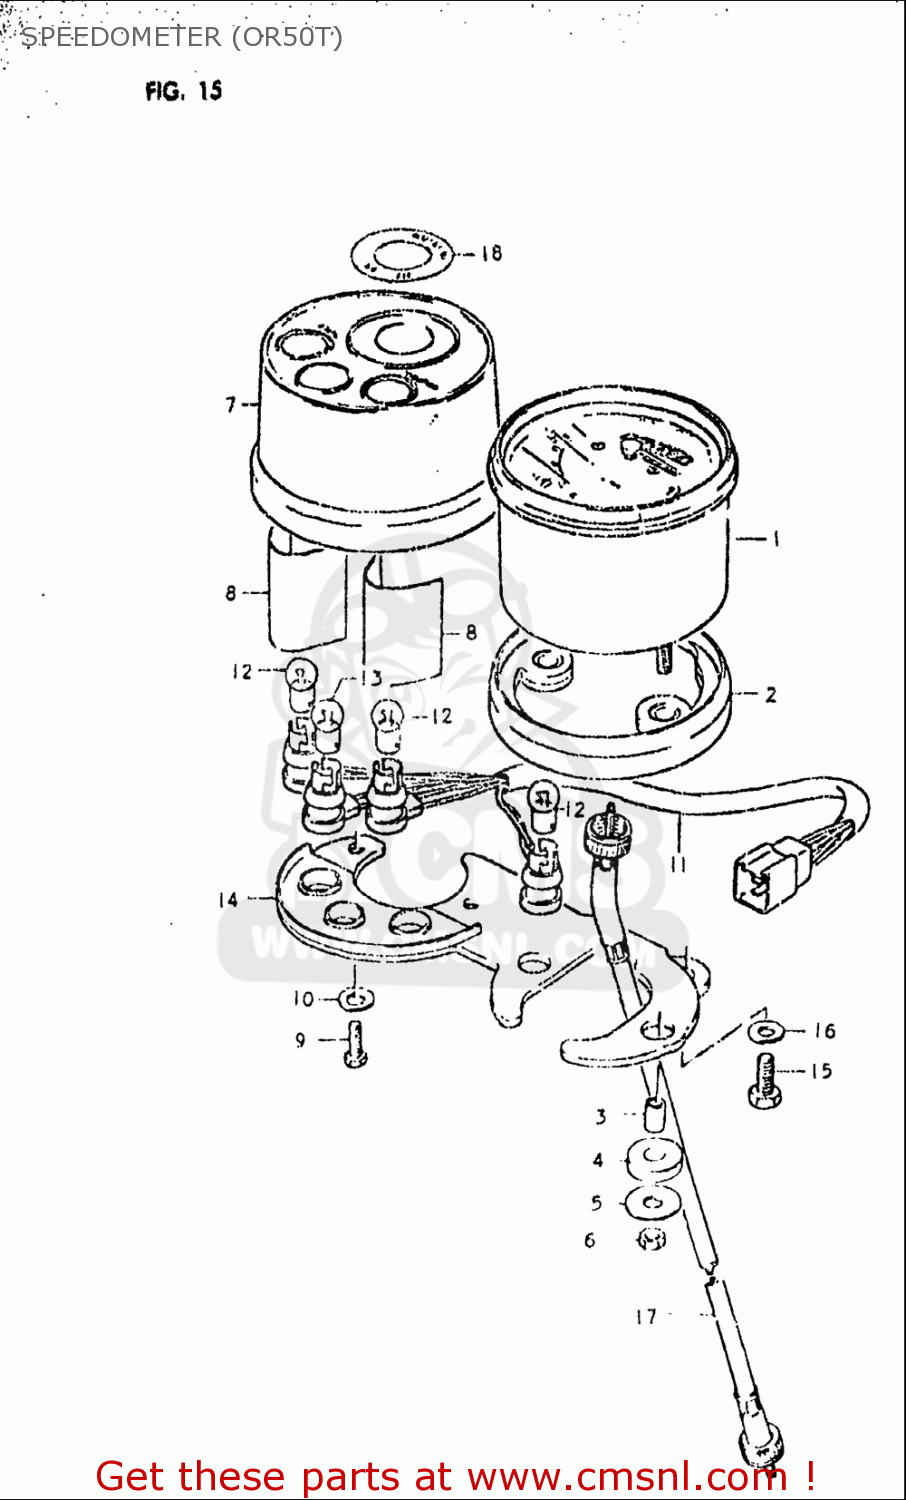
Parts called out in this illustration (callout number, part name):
5	WASHER (5.5X18X1.6)
6	NUT
9	BOLT
10	WASHER
11	SOCKET,METER
12	BULB(6V/3W)
13	BULB(6V1.7W,STANLEY,A61A)
15	BOLT
16	WASHER
